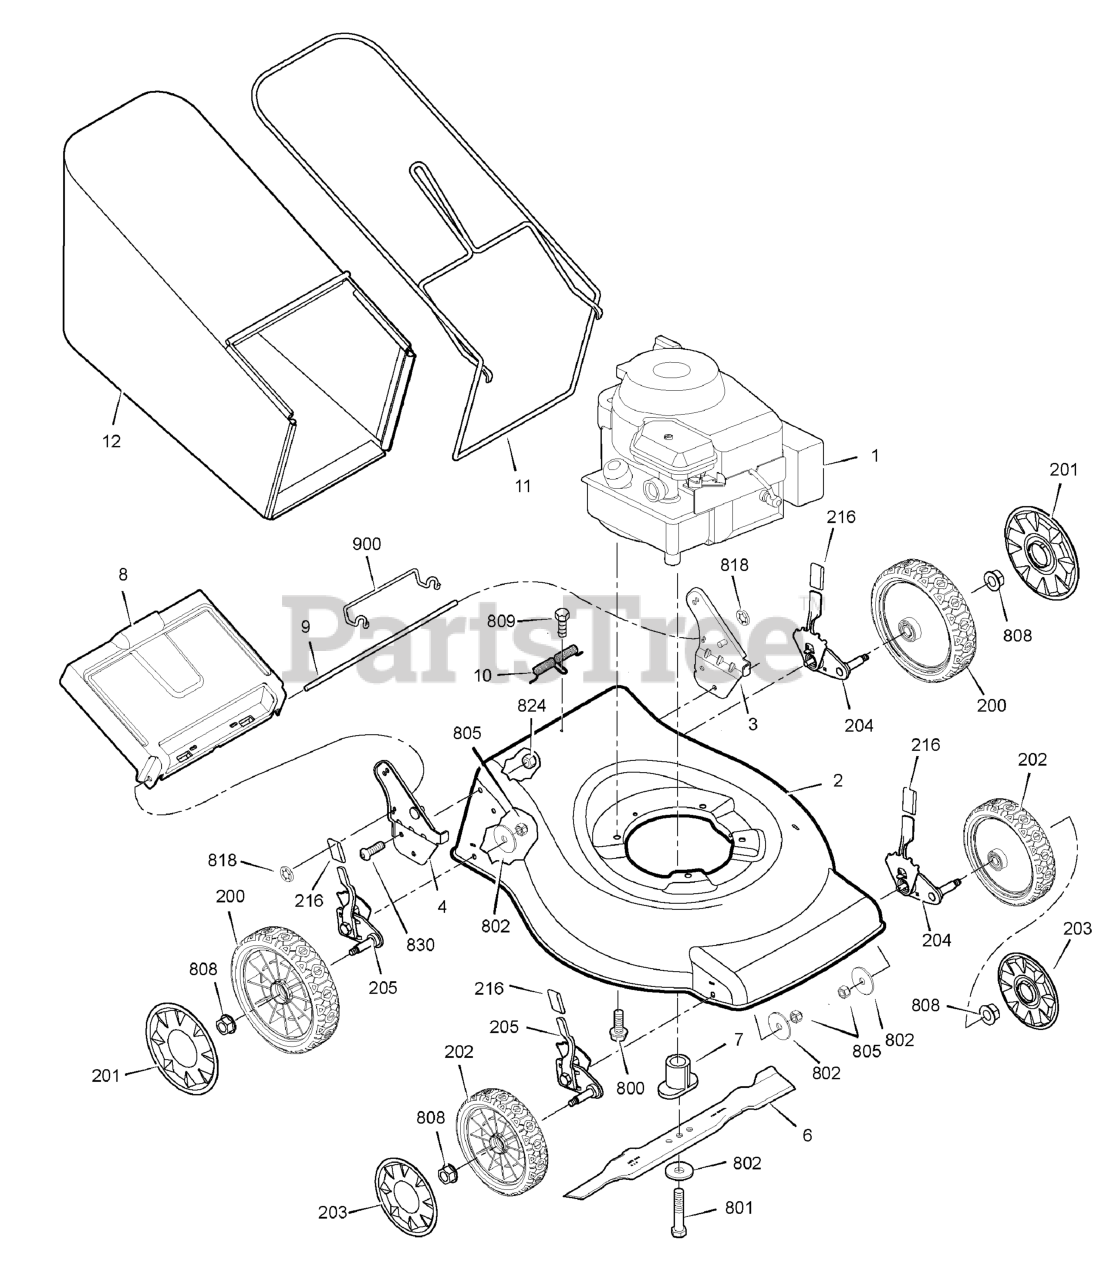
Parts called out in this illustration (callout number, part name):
1	* ENGINE
2	HOUSING ASSEMBLY
3	BRACKET ASSEMBLY, Left Handle
4	BRACKET ASSEMBLY, Right Handle
6	BLADE, 16 in
7	BLADE ADAPTER ASSEMBLY
8	DOOR, Rear
9	ROD, Rear Door
10	SPRING, Torsion Rear Door
11	FRAME ASSEMBLY
12	BAG ASSEMBLY
200	WHEEL, Rear
201	HUBCAP, Rear
202	WHEEL, Front
203	HUBCAP, Front
204	HEIGHT ADJUSTER ASSEMBLY, Left
205	HEIGHT ADJUSTER ASSEMBLY, Right
216	GRIP, Height Adjustment
800	SCREW, Hex Head, 3/8-16 x 1
801	BOLT, Blade, 3/8-24 x 2
802	WASHER, Belleville
805	NUT, Nylock, M8 x 1-1/4
808	NUT, Flange, 3/8-16
809	SCREW, Self Tap, #10-16 x 1/2
818	NUT, Speed
822	NUT, Hex, 1/4-20
824	NUT, Flange, 5/16-18
830	SCREW , 5/16-18 x 3/4
900	SPRING CLIP, Rear Door
1000	DECAL KIT
1001	MANUAL KIT
